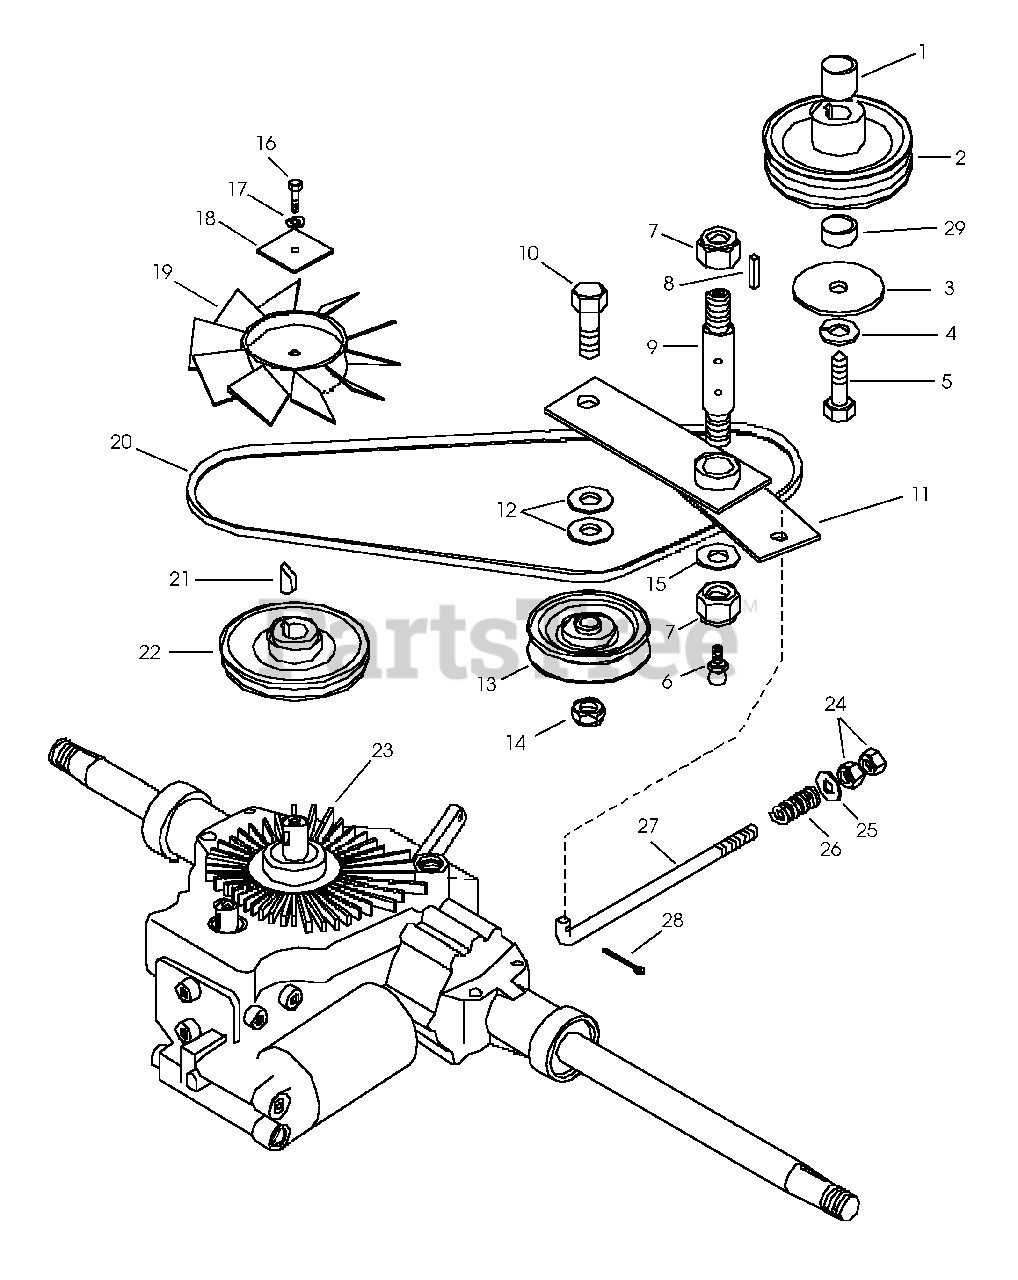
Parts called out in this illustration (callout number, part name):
1	Bushing-Sleeve 1.13 x 1.38 x 1.25
2	Sheave
3	Washer-Special .469 x 2.000 x .250
4	Washer-Locking .44 x 1.09
5	Bolt-Hex .44-20 x 1.50
6	Fitting-Lube 1/8
7	Nut-Locking-Center .62-11
8	Key-Square .248 x 1.25 x .248
9	Pin-Pivot
10	Bolt-Hex .38-16 x .50 Grade 5
11	Weldment-Idler Arm
12	Washer-Flat-Steel .531 x 1.06 x .095
13	Pulley-V 4.00 x .84
14	Nut-Locking-Center .50-13
15	Washer-Flat-Steel .656 x 1.31 x .095
16	Bolt-Hex .25-20 x 1.25 Grade 5
17	Washer-Lock .25 x .062
18	Washer-Flat-Steel .265 x 1.75 Square x .119
19	Fan
20	V-Belt A-Section 18.05 x .495
21	Key-Woodruff .19 x .63
22	Pulley-Drive
23	Transaxle-Eaton #851-109
24	Nut-Hex .375-16
25	Washer-Flat-Steel .406 x .812 x .065
26	Spring-Compression .072 x .561 x 2.50
27	Rod-Idler
28	Pin-Cotter .09 x .75
29	Spacer 1.137 x 1.50 x .656
